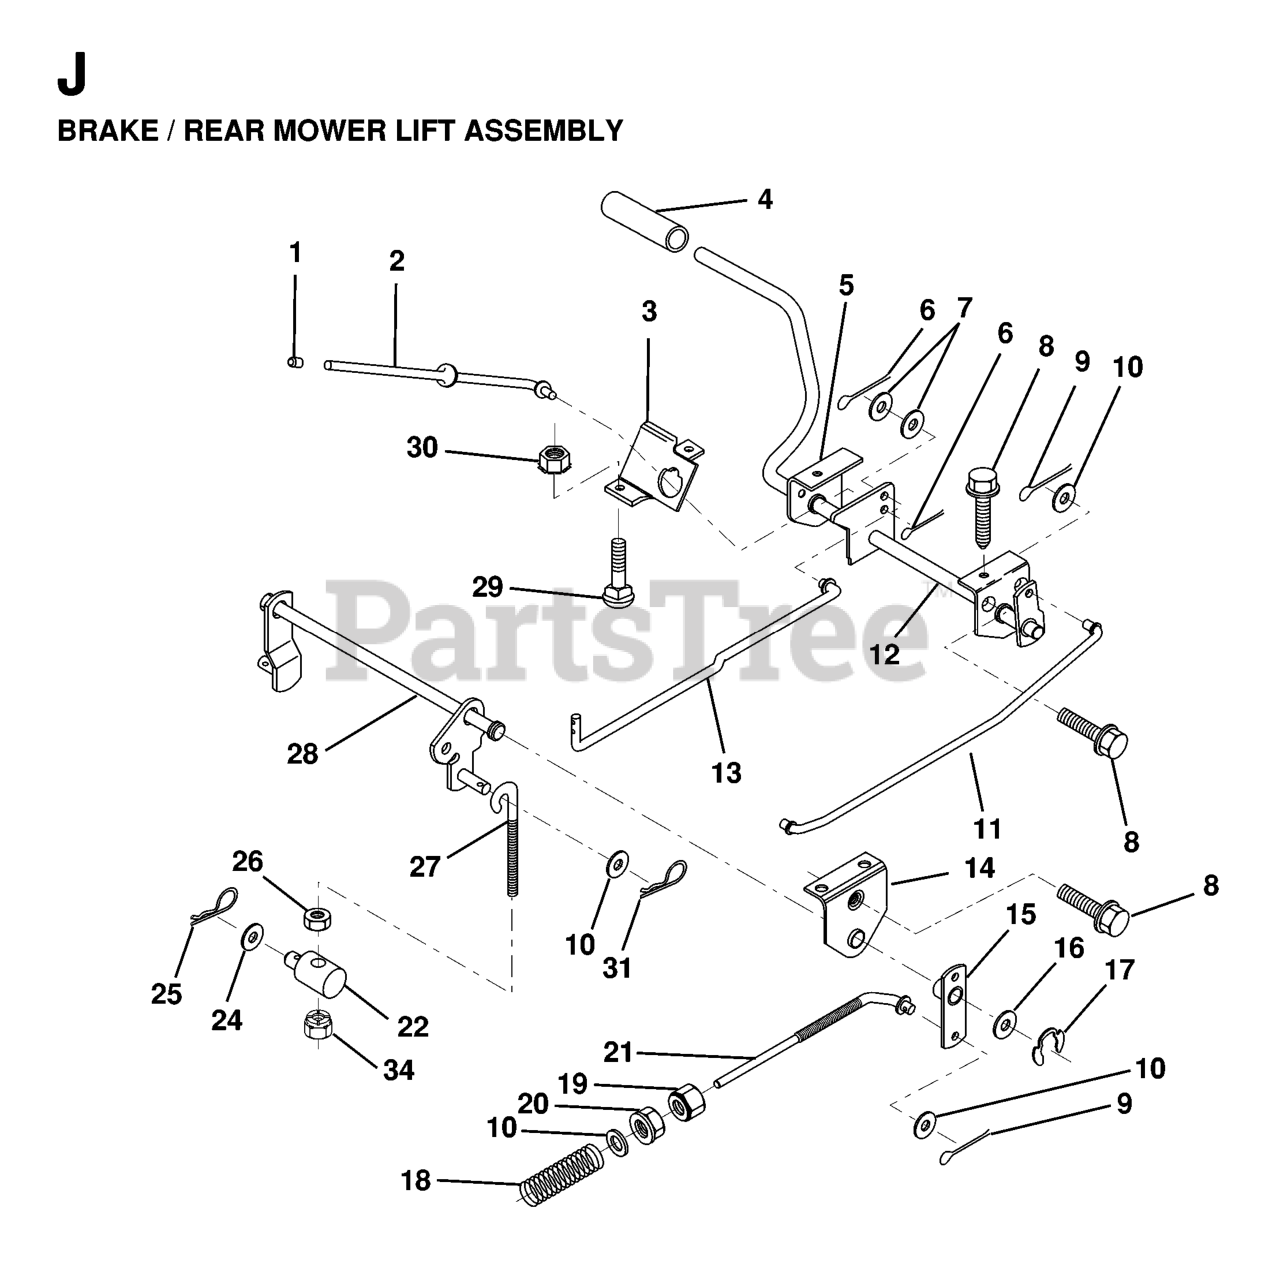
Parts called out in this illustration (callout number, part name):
1	PLUNGER CAP
2	ROD,PARK BRAKE
3	BRKT,PARK BRAKE
4	FOOT PEDAL COVER
5	BRKT,CLU PEDAL LH
6	COTTER PIN
8	Screw 5/16-18 x 1/2 Hex, Self Tapping 5/16-18 x 1/2
9	COTTER PIN
10	WASHER
11	ROD,FRT BRAKE
12	CLUTCH/BRAKE PEDAL ASSY
13	ROD,CLUTCH
14	BRKT,LIFT SHAFT
15	ARM, BRAKE ASMBLY
17	Ring, Klip Truarc #5304-75
18	SPRING, BRAKE ROD
19	NUT
20	NUT
21	ROD REAR BRAKE
22	TRUNNION, LEFT
24	WASHER
25	SPRING TI
26	LOCKNUT
27	LINK.MOWER.REAR
28	REAR MOWER LIFT ASSY
29	BOLT.CARR.SQNK.5/16-18UNC.X3/4
30	NUT
31	SPRING RETAINER
